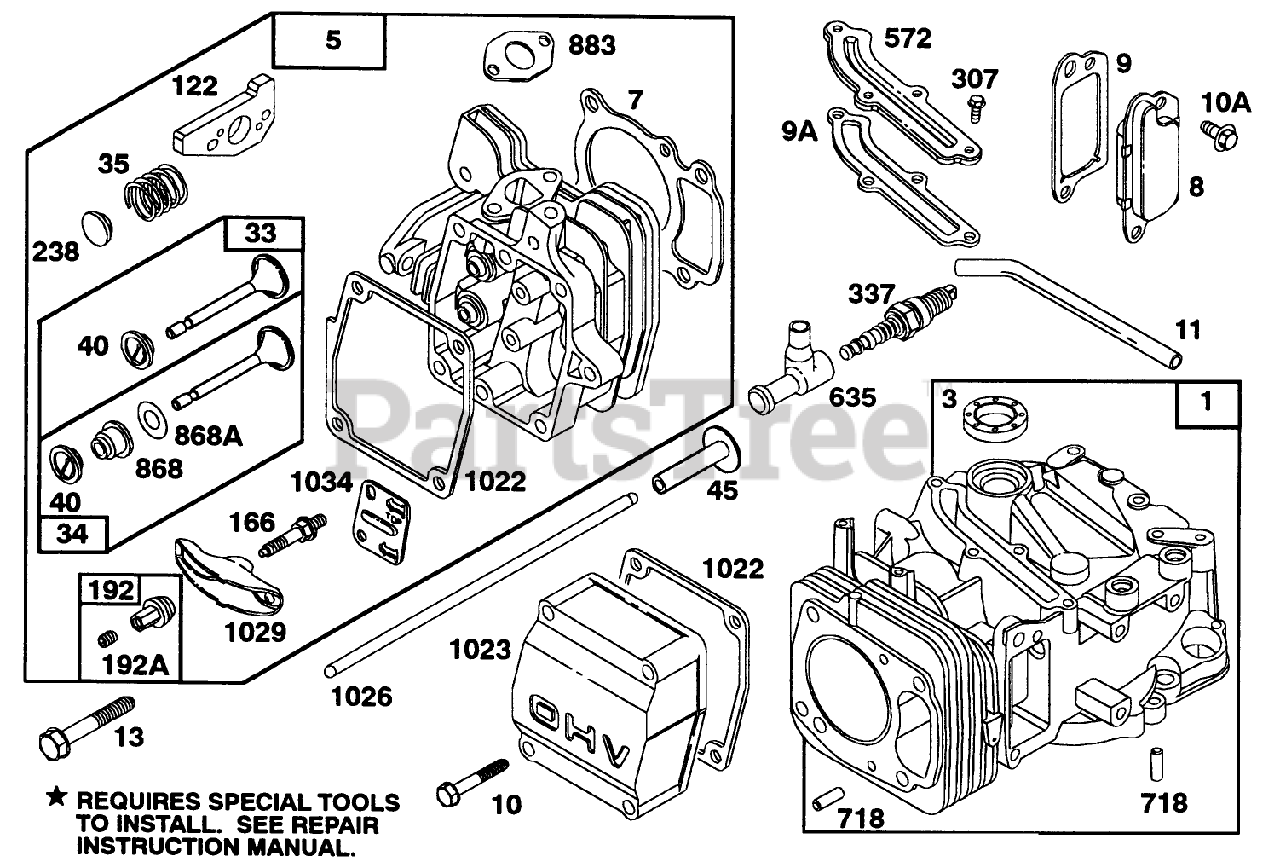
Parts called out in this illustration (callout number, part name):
3	SEAL - OIL
7	CYLINDER HEAD GASKET
9	VALVE - SHUT-OFF
9A	GASKET-BREATHER
12	ENGINE BASE GASKET
20	SEAL-OIL
104	FLOAT HINGE PIN
116	SEALING GASKET
116A	O RING SEAL
118	VALVE KIT - NEEDLE
121	CARBURATOR OVERHAUL KIT
122	ADAPTER ASSEMBLY
127	PLUG
134	Valve-Inlet (Includes Seat)
137	FLOAT BOWL GASKET
163	AIR CLEANER GASKET
358	GASKET SET
524	O-RING
634	SEAL WASHER
842	O-RING
868	SealAssy-Valve
868A	Seal-Valve
883	EXHAUST GASKET
977	CARBURATOR GASKET SET
1022	ROCKER COVER GASKET
1039	FLOAT LIMITER
